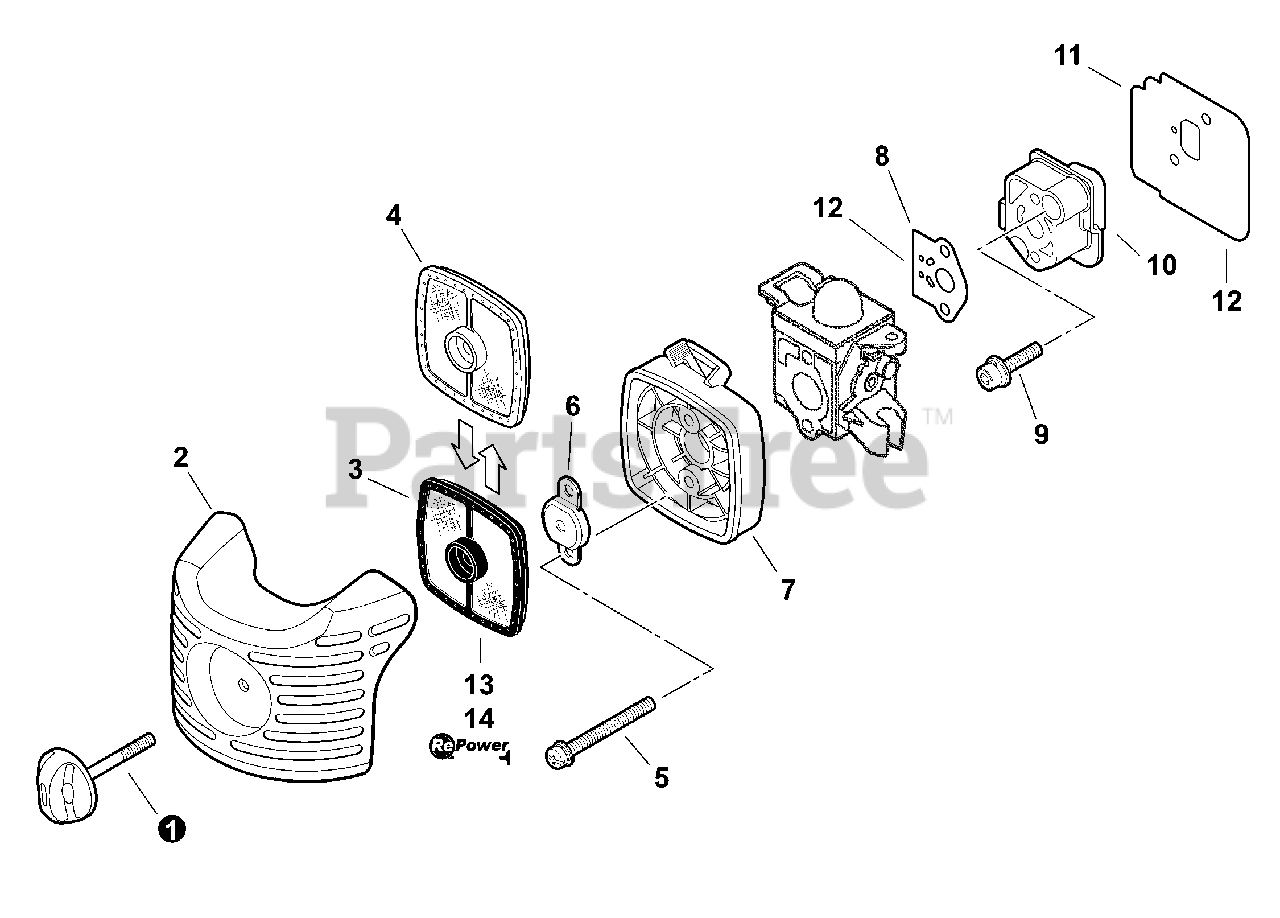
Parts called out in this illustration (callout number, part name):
1	THUMBSCREW
2	COVER, AIR FILTER
3	FILTER, AIR - DOUBLE LAYER
4	FILTER, AIR - SINGLE LAYER
5	SCREW 5×65
6	PLATE, PREVENT
7	CASE ASSY, AIR FILTER
8	GASKET, INTAKE
9	INSULATOR, INTAKE
10	BOLT 5×25
11	HEAT SHIELD, INTAKE
12	GASKET KIT
13	FILTER KIT - REPOWER
14	TUNE-UP KIT - REPOWER
